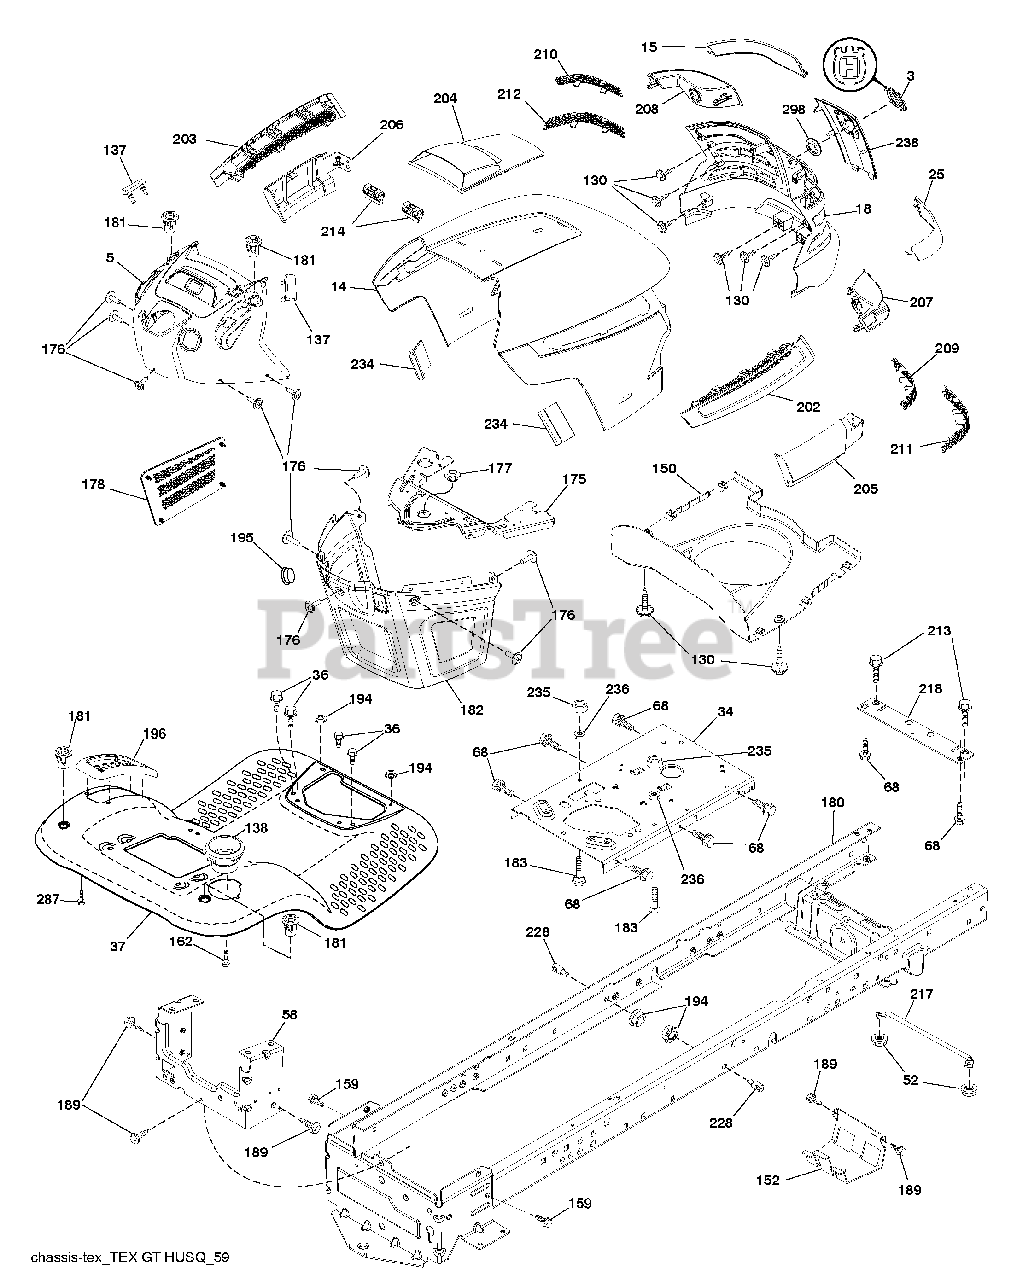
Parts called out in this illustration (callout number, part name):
3	Logo Crown
14	Hood
18	Grille/Lens Asm.
34	Plate Engine
36	Screw 5/16-18 x 3/4
37	Fender
52	Nut Lock 5/16-18
58	Drawbar Upper
68	Screw Thdrol 5/16-18 x 1/2
130	Screw #10 x 0.750 BOS Thread
137	Bumper Dash
138	Cupholder
152	Shield Browning
159	Screw Hexwsh Thdr 3/8-16 x 3/4
175	Crossmember
176	Screw 10-24 x 5/8
177	Bushing Steering
178	Cargo Net Asm.
181	Bushing Mtg. Fender Crgo
182	Dash Lower
183	Bolt 5/16-18 x 1-1/4 Full Thread
189	Screw 5/16-18 x 3/4
194	Nut Lock Hex Flange 5/16-18
195	Plug Hole Dash Lower
196	Console Asm. Deck Lift
202	Vent Side Hood RH
203	Vent Side Hood LH
204	Vent Top Hood
205	Skirt Hood Side RH
206	Skirt Hood Side LH
209	Insert Hex Top RH
210	Insert Hex Top Lh
211	Insert Hex Bottom RH
212	Insert Hex Bottom LH
213	Bolt 5/16-18 x 3/4
214	Clip Retainer Tinner
218	X-Piece Hood Stop
228	Stud Fastner
234	Bumper Hood
235	Spacer Fender
236	Nut Lock 5/16-18 unc
238	Trim Husq.
287	Screw Hex Washead 1/4-20 x 3/8
